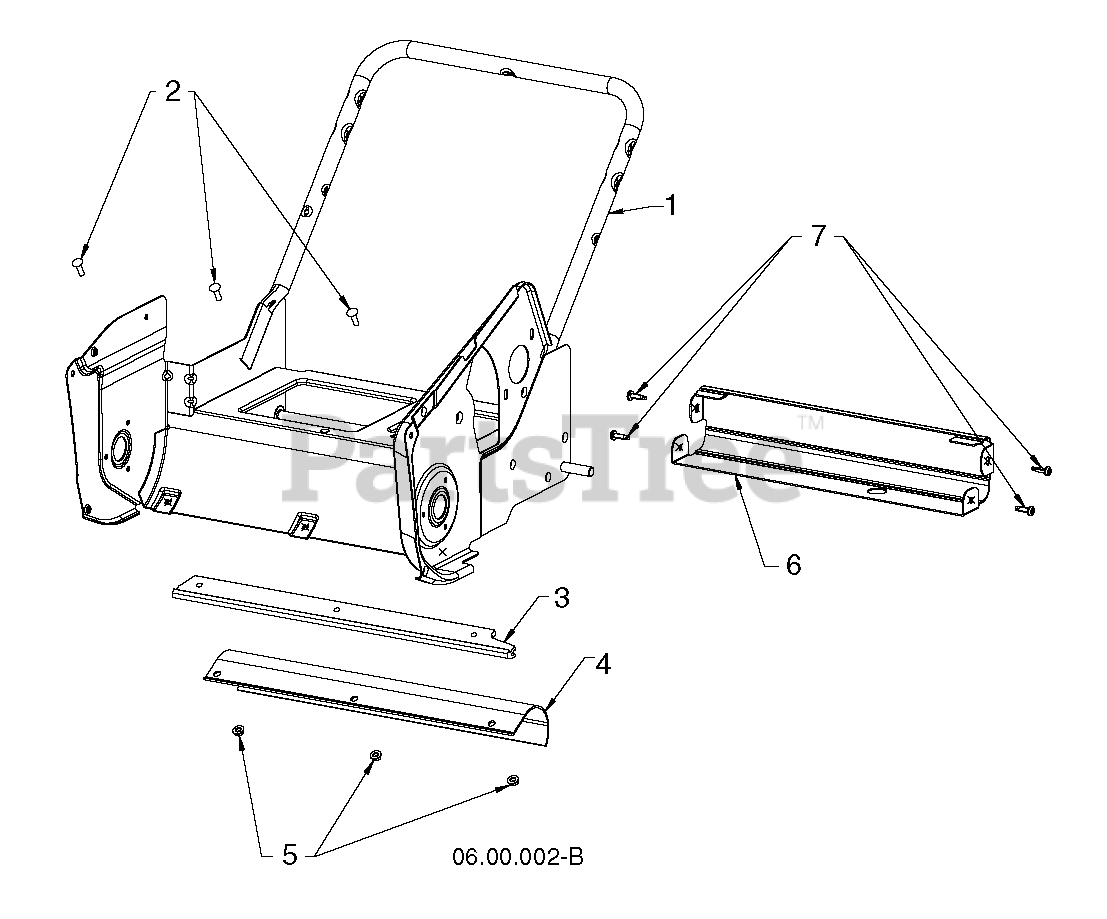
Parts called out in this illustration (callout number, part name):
1	FRAME.WELDMENT.GREY
2	BOLT.CARRIAGE.1/4-20 X 7/8
3	BAR.SCRAPER.SINGLE.STAGE.GREY
4	SKIRT.SCRAPPER-SSST
5	NUT.HEX.FLANGE.1/4
6	SUPPORT.SSST.REAR.FRAME.GREY
7	SCREW.PAN.HD.TORX.1/4-20X.750
